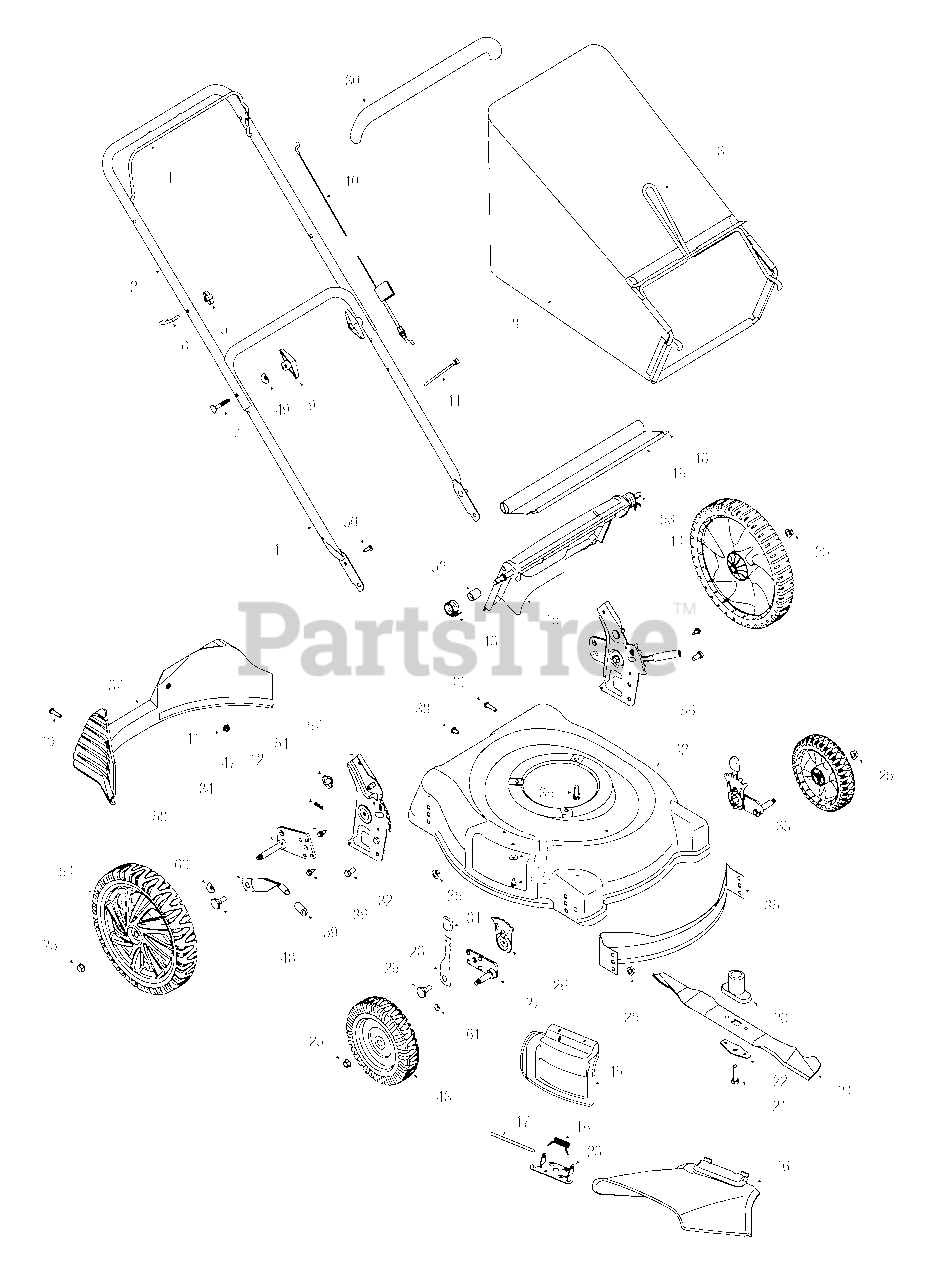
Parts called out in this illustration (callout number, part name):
5	Wing Nut
6	Rope Guide
7	Carriage Bolt 5/16-18 x 2"
8	Grass Bag
9	Handle Knob
10	Control Cable 40"
11	Cable Ties
12	Hairpin Clip
13	Torsion Spring - Right Hand
14	Torsion Spring - Left Hand
15	Grass Bag Door
16	Torsion Spring
17	Hinge Pin
18	Wire Rod
19	Trailshield
20	Blade Adapter
21	Hex Cap Screw 3/8-24 x 2.5
22	Blade Bell Support
23	Chute Deflector Adapter
24	Blade: 21" Mulching
25	Flange Lock Nut 3/8-16
26	Height Adjustment Plate
27	Pivot Bar Assembly - Right Hand
28	Spring Lever
29	Shoulder Screw
30	Deluxe Bail Cover 22"
31	Spring Lever Knob
32	Hex Screw 3/8-16 x 0.75
33	Front Height Adjuster Assembly - Right Hand
34	Pivot Bar Assembly - Right Hand
35	Front Baffle
36	Hex Washer Screw 3/8-16 x 1.0
37	Rear Baffle 21" Rd.
38	Machined Screw 1/4-20
39	TT Screw 1/4-14 x .625
40	Hex Screw 1/4-15
41	Flange Lock Nut 1/4-20
44	Bell Washer .265 ID x .75 OD
45	Hinged Mulch Plug Assembly
46	Side Discharge Deflector
47	Screw 1/4-20
48	Hex Cap Screw 3/8-16 x 1.0
49	Shoulder Washer .320 ID x .930 OD
50	Hex Carriage Screw 1/4-20
51	Wing Nut
52	Spacer .375 O.D. x .50 I.D. x 1.02"
53	Chute Door Pivot Rod
54	Rear Wheel: Zag Trd. Gray 12 x 2.125
56	Handle Bracket Assembly - Left Hand
57	Handle Bracket - Left Hand
58	Spring Lever
59	Spring Lever Knob
60	Spring Washer.500 x 1.00 x.022
61	Wave Washer.510 x.750 x.017
